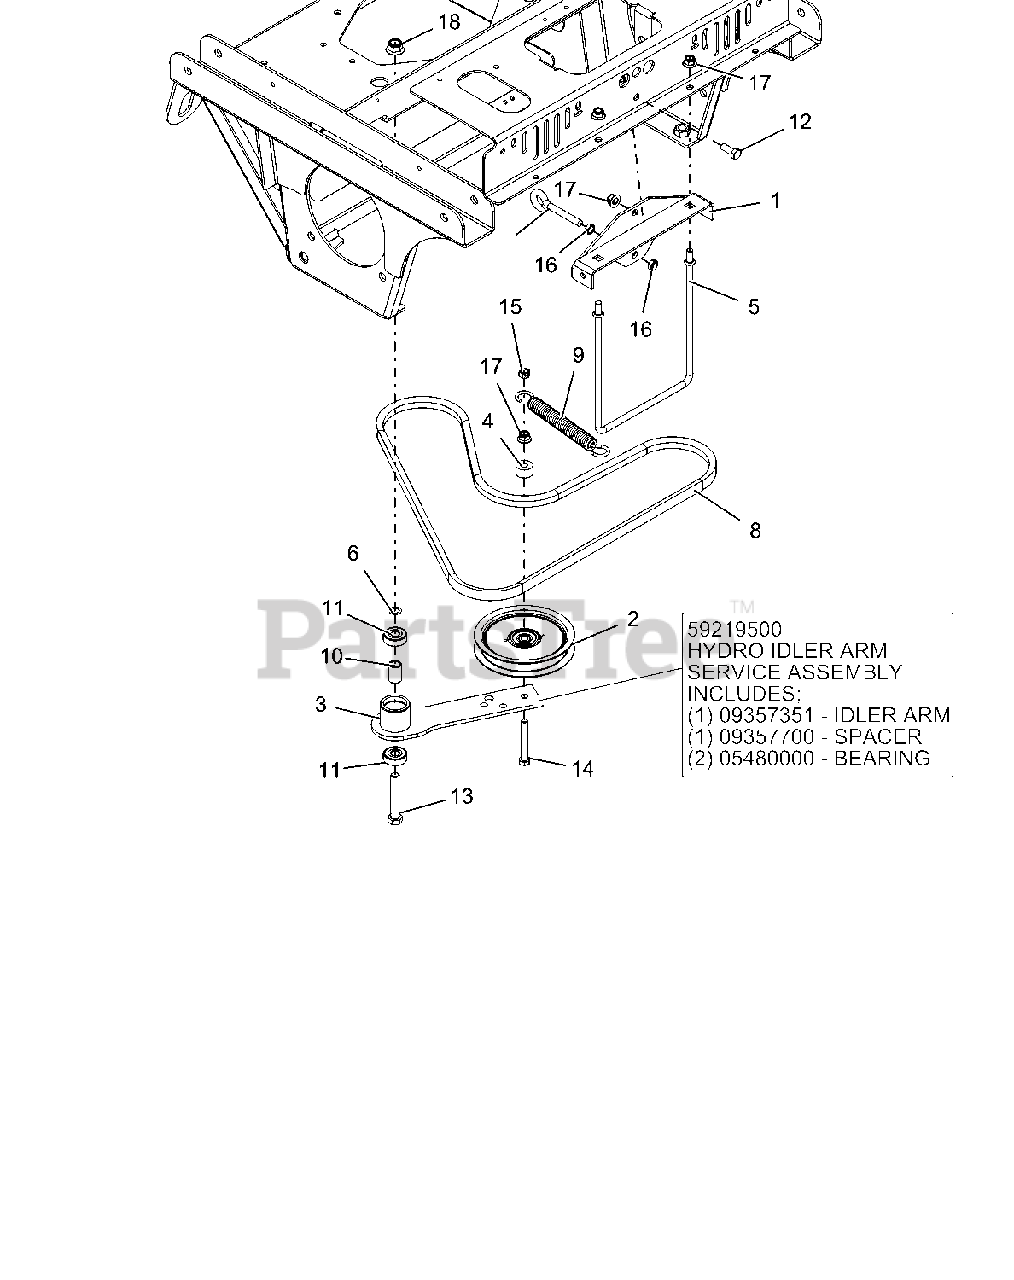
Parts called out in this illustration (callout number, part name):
1	WMT, SPRING ANCHOR BRKT-BLACK
2	IDLER, FLAT - 5.00" X .75"
3	HYDRO IDLER ARM SERVICE ASSEMBLY
3	IDLER ARM
3	SPACER
3	BEARING
3	WLDMT, HYDRO DRIVE IDLER ARM-BLACK
4	SPACER .390X1.000X.562
5	ROD, BRAKE MTG
6	WASHER-FLAT-STL, .500 X .750 X .020
7	BOLT, EYE .375-16
8	BELT, B RAW COGGED
9	SPRG, EXTENSION - SWIVEL
10	SPACER, .510 X .750 X 1.148
11	BRG-BALL .500X1.375X.44
12	BLT-HEX .38-16X1.00 GR5 YWZC
13	BLT-HEX .50-13X3.00 GR5 YWZC
14	BLT-HEX .38-16X2.75 GR5 YWZC
15	NUT-LK-CTR .38-16 YWZC
16	NUT, JAM .375-16 YWZC
17	NUT-LK-NYL-FLG .38-16 YWZC
18	NUT-LK-NYL-FLG .50-13 YWZC
